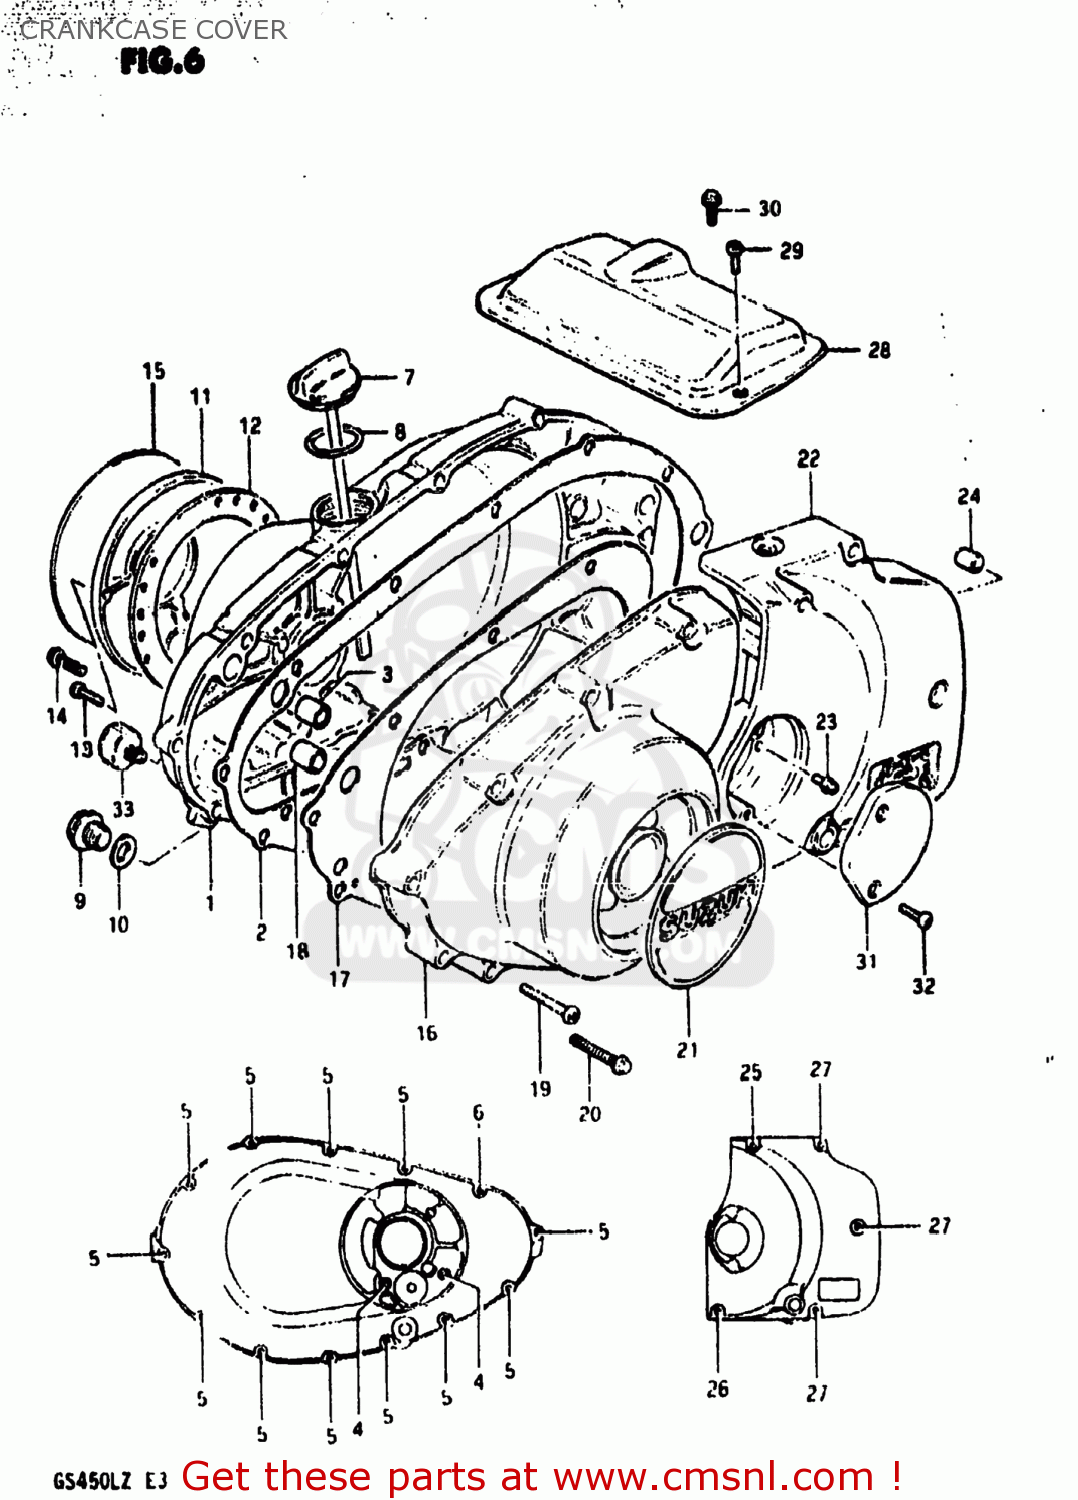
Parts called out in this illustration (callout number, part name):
1	COVER,CLUTCH
2	GASKET,CLUTCH COVER (MCA)
3	PIN
4	SCREW
5	BOLT (6X35)
6	BOLT
7	GAUGE,OIL LEVEL
8	O-RING
9	PLUG (14X12)
10	GASKET(14X19.2X2) (NAS)
11	COVER,CONTACT BREAKER
12	GASKET,CONTACT BREAKER COVER (NAS)
13	SCREW
14	BOLT 5X16
15	EMBLEM,MAGNETO COVER
16	COVER
17	GASKET,MAGNETO COVER (MCA)
18	PIN
19	SCREW (6X35)
20	BOLT (6X35)
21	EMBLEM,MAGNETO COVER
22	COVER,SPROCKET
23	NIPPLE
24	PIN
25	SCREW 6X65
26	SCREW
27	SCREW
28	COVER,STARTER MOTOR
29	SCREW
30	BOLT (5*8)
31	CAP,CLUTCH RELEASE ADJUST
32	SCREW 5X12
33	SWITCH ASSEMBLY
